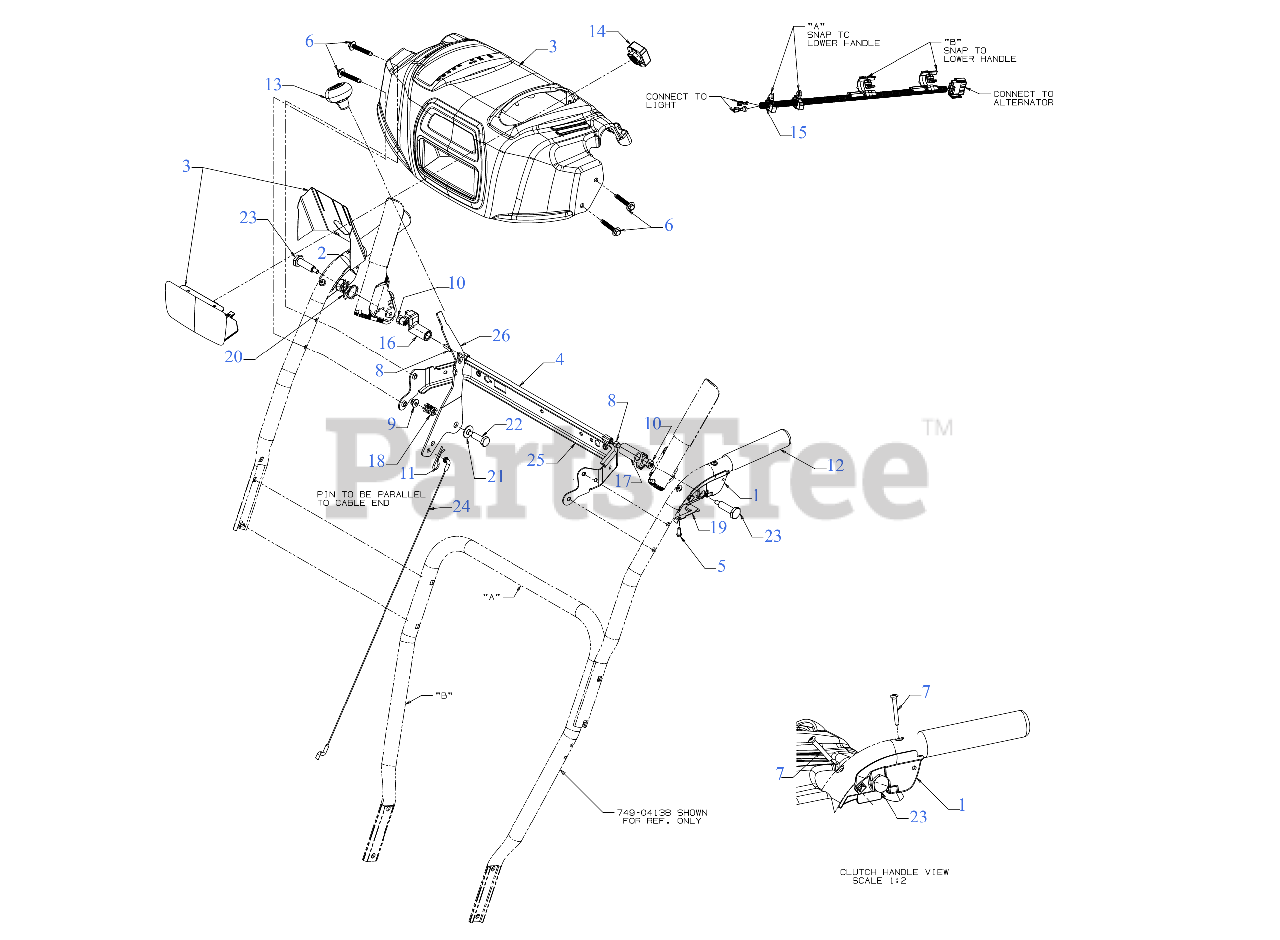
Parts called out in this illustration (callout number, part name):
1	CLUTCH LOCK HANDLE ASSEMBLY (LH)
2	CLUTCH LOCK HANDLE ASSEMBLY (RH)
3	HANDLE PANEL ASSEMBLY
4	PIVOT ROD
5	SCREW #8-16 x .50
6	SCREW 1/4-20 x 1.625
7	SCREW #10-24 x 1.375
8	SCREW 1/4-20 x .50
9	FLANGE LOCK NUT
10	HEX NUT W/PATCH
11	INTERNAL COTTER PIN
13	SHIFT KNOB
14	LED HEADLIGHT SOCKET (150 LUMNES)
15	LIGHT HARNESS
16	LOCK PLATE
17	CLUTCH LOCK CAM
18	COMPRESSION SPRING
19	CLUTCH SPRING
20	TORSION SPRING
21	FLAT WASHER .40X.88X.060
22	SHOULDER SCREW
23	SHOULDER SCREW .437 x 1.345 1/4-20
24	SPEED SELECTOR CABLE (PLASTIC)
25	HANDLE SUPPORT BRACKET (POWDER BLACK)
26	SHIFT LEVER
